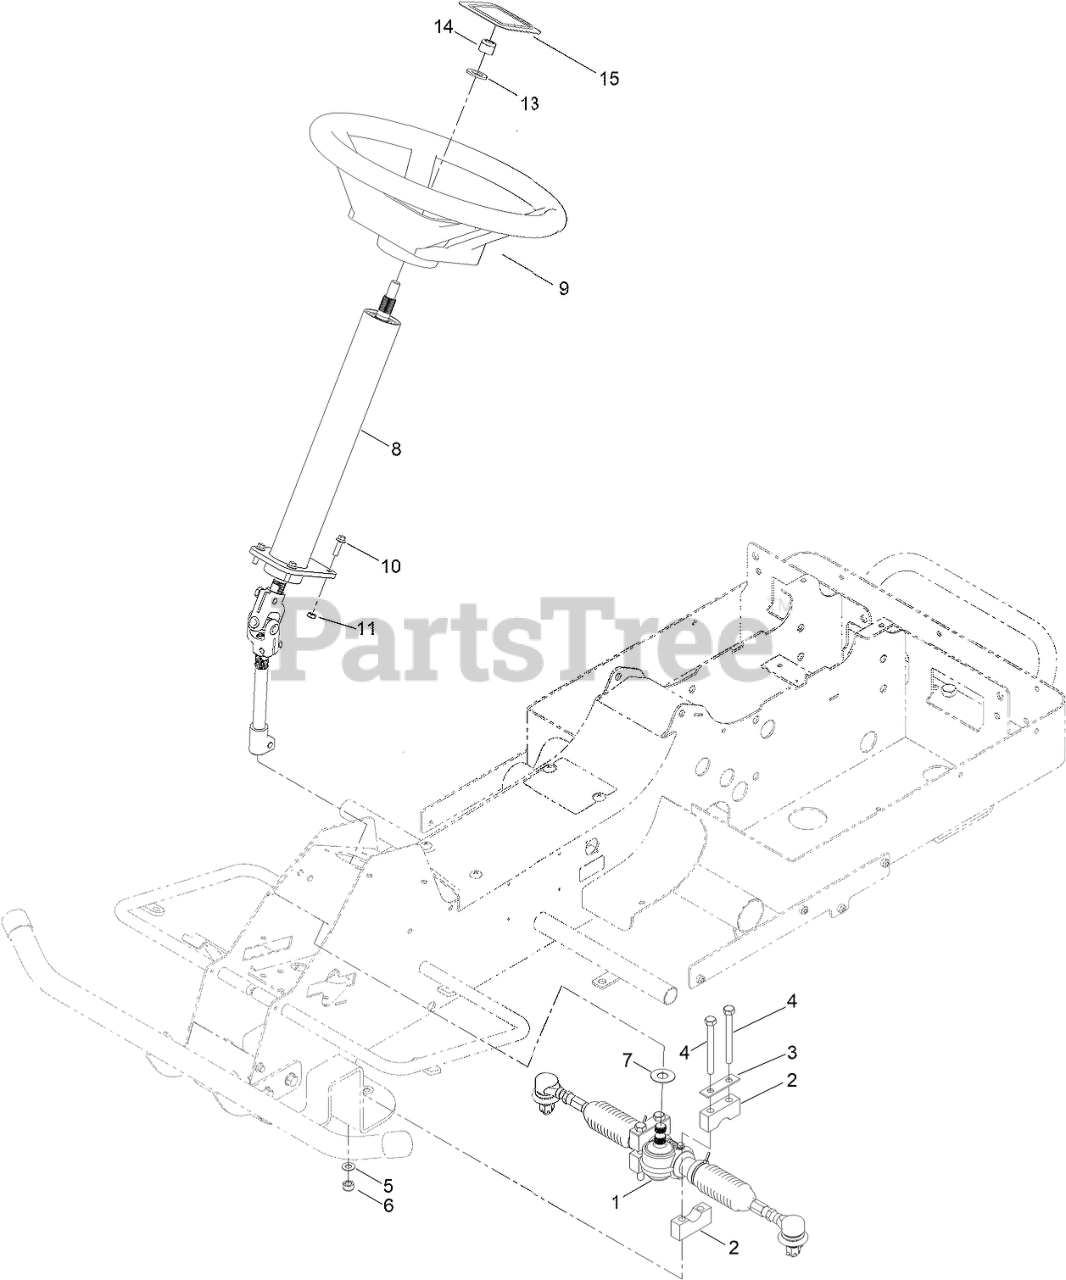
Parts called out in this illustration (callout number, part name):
1	STEERING RACK ASM
2	MOUNTING BLOCK, STEERING RACK
3	PLATE, MOUNTING BLOCK
5	WASHER-PLAIN
6	NUT-HEX, NI
7	WASHER
8	STEERING ROD ASM
9	STEERING WHEEL
10	BOLT-M6
11	NUT-M6
13	WASHER-PLAIN
14	NUT-NYLOC
15	COVER, STEERING WHEEL
